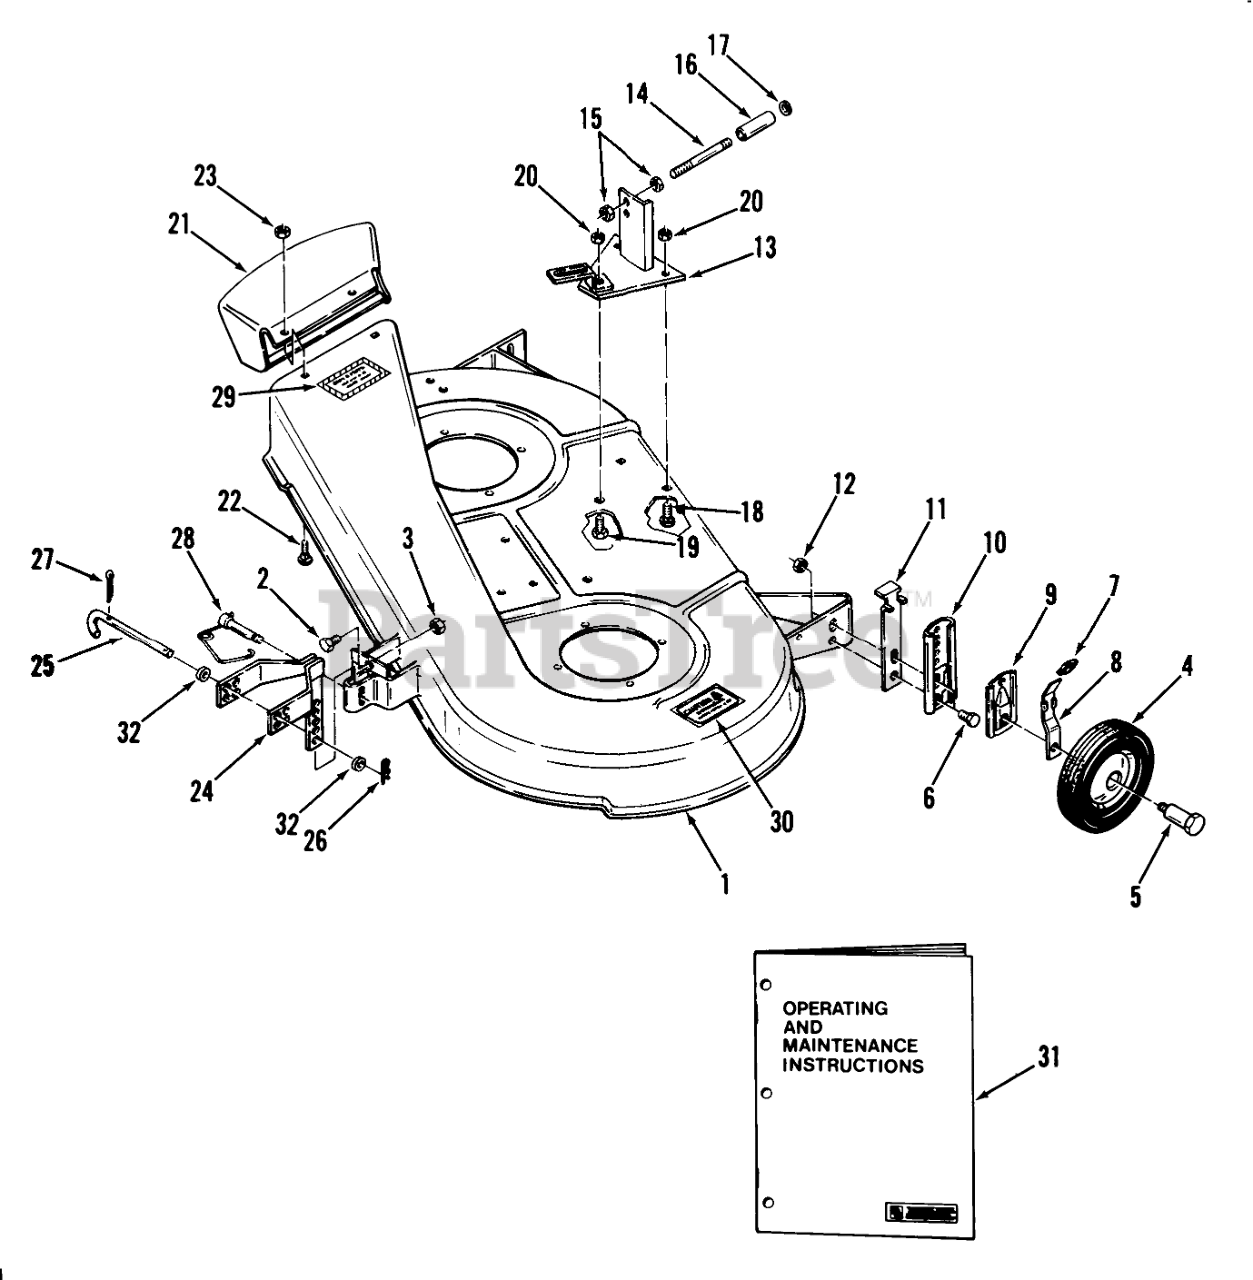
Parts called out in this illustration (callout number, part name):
8	HT ADJ SPRING LEVER
9	HT ADJ SLIDE
22	CARRIAGE BOLT -4
26	Hairpin Cotter
31	Operating and Maintenance Instructions
32	WASHER-FLAT
